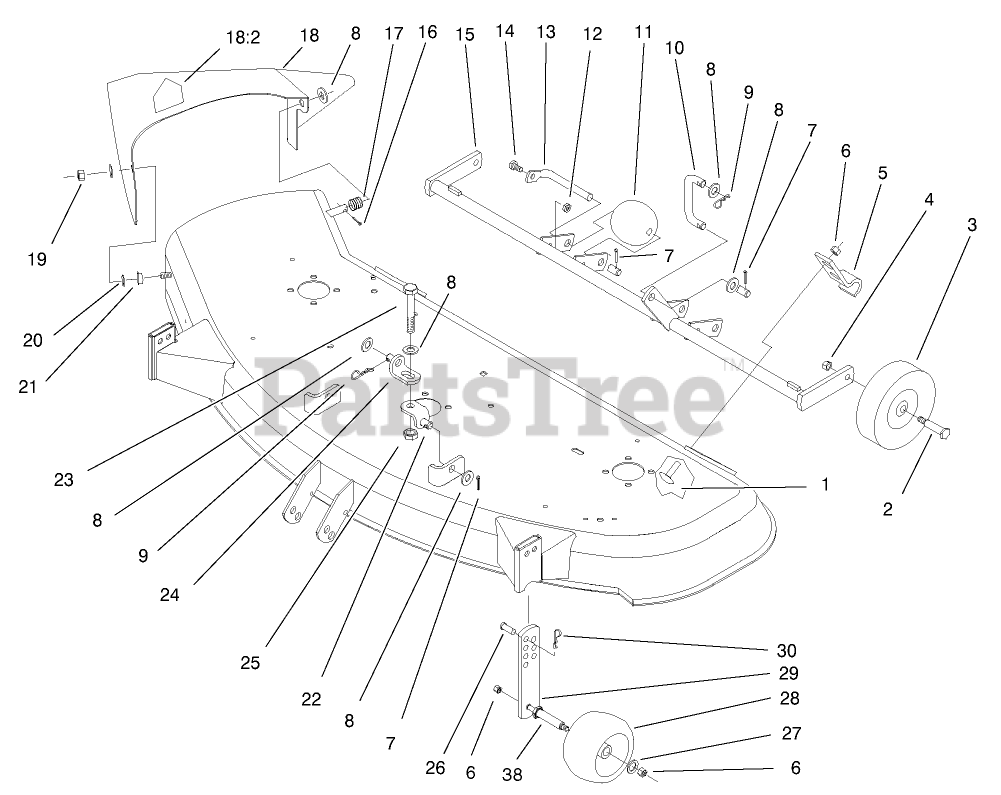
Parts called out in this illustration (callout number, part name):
1	BOLT-CARR
2	BOLT-SHOULDER
3	WHEEL
4	NUT-HEX
5	BRACKET-PIVOT
6	NUT-LOCK, NI
7	PIN-COTTER
8	WASHER-FLAT
9	PIN-COTTER, HAIR
10	LINK-REAR
11	ROLLER
12	NUT-LOCK, NI
13	Shaft-Roller
14	SCREW-HH
15	SUPPORT-GAGE WHEEL
16	PIN-COTTER
17	SPRING-DEFLECTOR
18	CHUTE ASM
18:2	DECAL-DANGER
19	NUT-HJ
20	WASHER
21	BUSHING-PIVOT
22	BRACKET-LIFT, UPPER
23	SCREW-HH
24	BRACKET-LIFT, LOWER
25	NUT-JAM
26	PIN-CLEVIS
27	WASHER-FLAT
28	WHEEL-GAGE
29	PLATE-GAGE WHEEL
30	PIN-HAIR
38	SPACER
